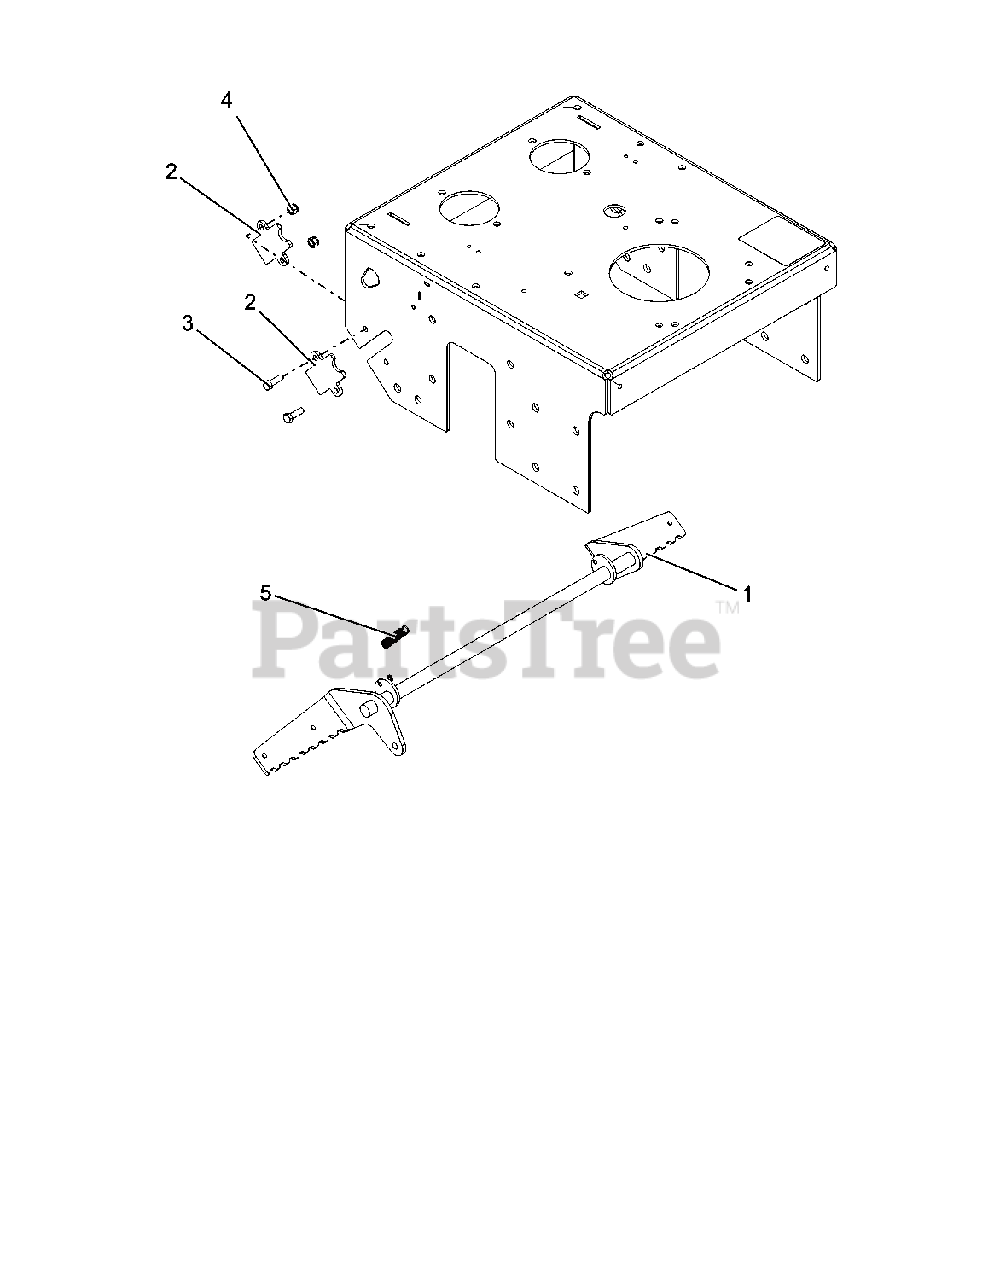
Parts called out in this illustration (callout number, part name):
1	WLDMT, BRAKE SYS 36" FLWLK
2	SHOE, BRAKE SYSTEM FLOAT WALK-RED
3	BLT-HEX .31-18X1.00 GR5 YWZC
4	NUT-LK-NYL .312-18 YWZC
5	SPRG, EXTENSION
